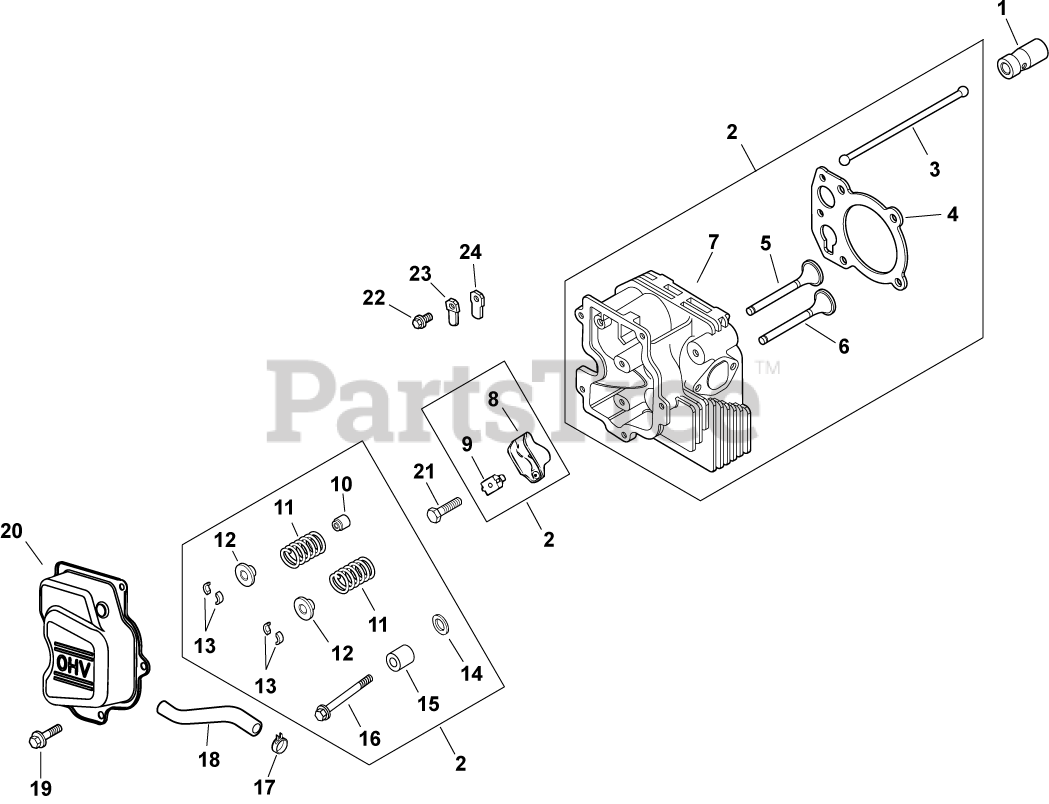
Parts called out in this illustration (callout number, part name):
1	LIFTER, HYDRAULIC VALVE-USE 25 351 10-S
2	KIT, CYLINDER HEAD HARDWARE
3	ROD, PUSH - DISCONTINUED
4	GASKET, CYLINDER HEAD
5	VALVE, INTAKE
6	VALVE, EXHAUST
7	HEAD ASSEMBLY, CYLINDER - DISCONTINUED
8	ARM, ROCKER
9	PIVOT, ROCKER ARM
10	SEAL, VALVE STEM - (#2503214S)
11	SPRING, VALVE
12	RETAINER, VALVE SPRING - USE 25 173 28-S
13	KIT, RETAINER
14	WASHER, FLAT 13/32"
15	SPACER, HEAD BOLT EXHAUST PORT
16	SCREW, CYLINDER HEAD (M10 X 80)
17	CLAMP, HOSE (KM)-USE 25 237 31-S
18	HOSE, BREATHER
19	SCREW,FLG THD FRM M6X1.0X16-(#25086397S)
20	COVER, ROCKER
21	SCREW, FLG M6X1.0X34
22	SCREW, FLG THD FRM M5X.8X10
23	RETAINER, REED
24	REED, BREATHER
